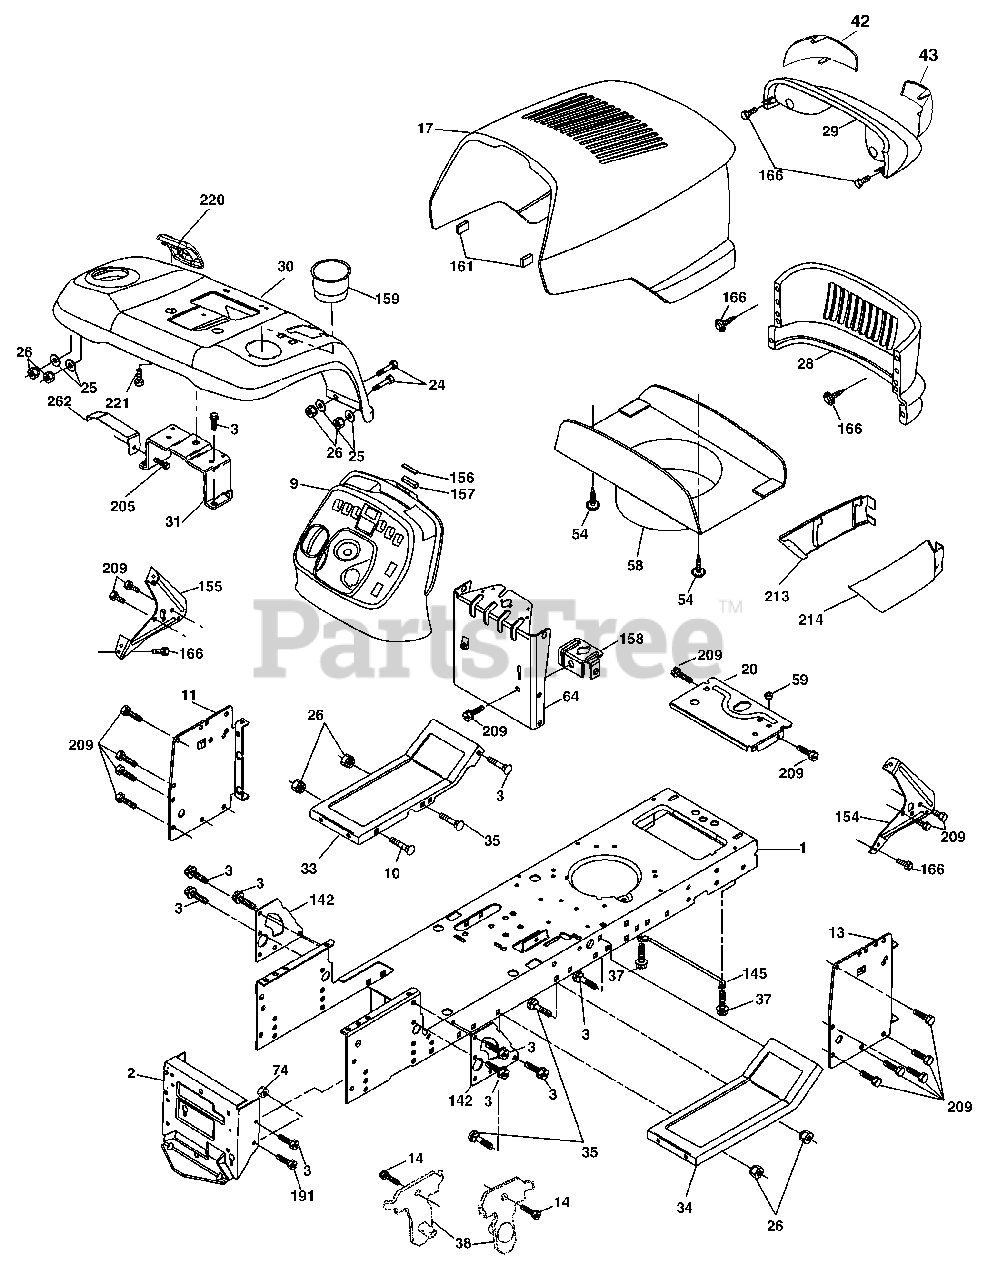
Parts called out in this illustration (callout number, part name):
1	Chassis
2	Drawbar
3	Screw 3/8-16x3/4
9	Dash
10	Bolt 3/8-16 x 1
11	Panel Dash Lh
13	Panel Dash Rh
14	Screw Thdrol 3/8-16 x 1/2
17	Hood
20	Plate Battery
24	Bolt 3/8-16 x 1 Gr. 5
25	Washer 13/32 X 13/16 X 12 Ga
26	Nut Lock Hex W/Ins 3/8-16 Unc
28	Grille
29	Light Box Asm W/Lens
30	Fender
31	Bracket Fender
33	Footrest LH
34	Footrest RH
35	Bolt 3/8-16 x 3/4
37	Screw Thdrol 6/16-18 x 1/2 TYT
38	Bracket, Asm. Pivot Mower Rear
42	Lens LH
43	Lens RH
54	Screw Hex Wshd 8-18 x 7/8
58	Duct Hood
59	Bushing Snap
64	Dash Lower
74	Nut Crownlock 3/8-16
142	Plate Reinforcement STLT
145	Rod Pivot Chassis/Hood
154	Bracket Dash Rh
155	Bracket Dash Lh
156	Striker Plate
157	Magnet Stealth
158	Bracket Parking Brake
159	Cupholder
161	Extrusion Bumper
166	Screw Hw Hd Hi-Lo #13-16 x 3/4
191	Bolt Fin Hex 3/8-16unc x 3/4 Gr. 5
205	Screw 3/8-16 x 1/2
209	Screw Hexwsh Thdrol 3/8-16 x 3/4
213	Skirt Grille Lh
214	Skirt Grille Rh
220	Console Fuel Window
221	Screw Hex Wsh Hi-Lo 1/4-1/2 Unc
262	Bracket Support Tank
